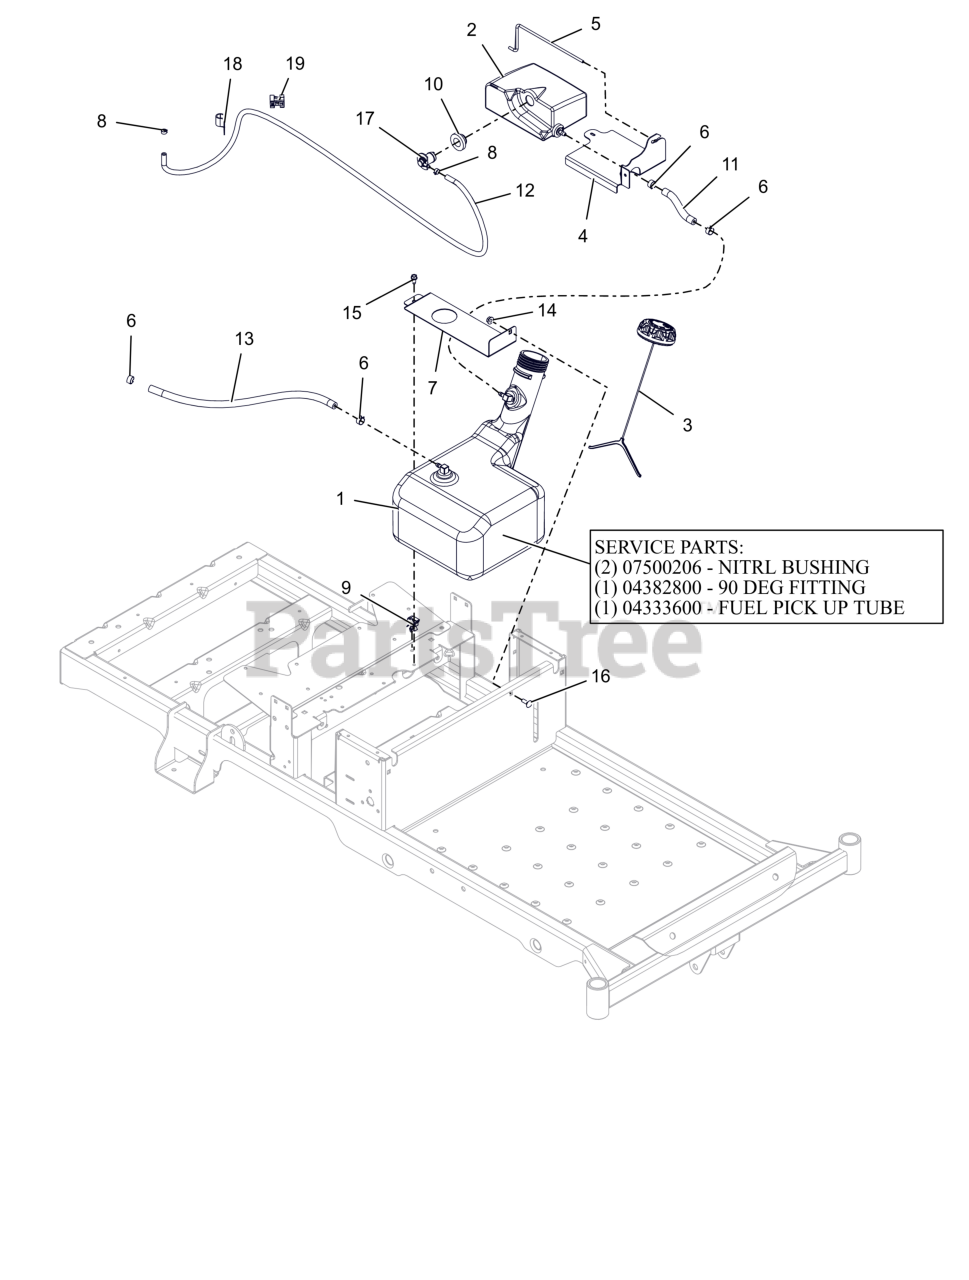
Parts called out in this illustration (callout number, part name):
1	ASM, FUEL TANK-ZOOM
1	BSHG-FLG .375X1.062X.625 NITR
1	FITTING, 90 DEG FUEL-PLASTIC
1	FUEL PICK UP TUBE
2	ASM, FUEL TANK - EXPANSION
3	CAP, FUEL VENT-IN 2.25" RATCH.
4	BRKT, EXPANSION TANK (ORANGE)
5	ROD, HOLDDOWN (BLACK)
6	CLAMP, FUEL LINE
7	BRKT, TANK STRAP
8	CLAMP-HOSE, SPRING .188
9	WIRE CLIP
10	GROMMET, REMOTE VENT NITRILE
11	HOSE, .25 LOW-PERM BULK GAS
12	HOSE, .188 LOW-PERM BULK GAS
13	HOSE, .25 LOW-PERM BULK GAS
14	NUT-LK-CTR-FLG .25-20 ZC120
15	SCR-TAP .25-20X.50 HWH ZCC
16	BLT, RHSN .25-20X.750 G5 ZCC
17	VALVE, 2-WAY
18	J-CLAMP
19	CLIP, T, .38-.50
